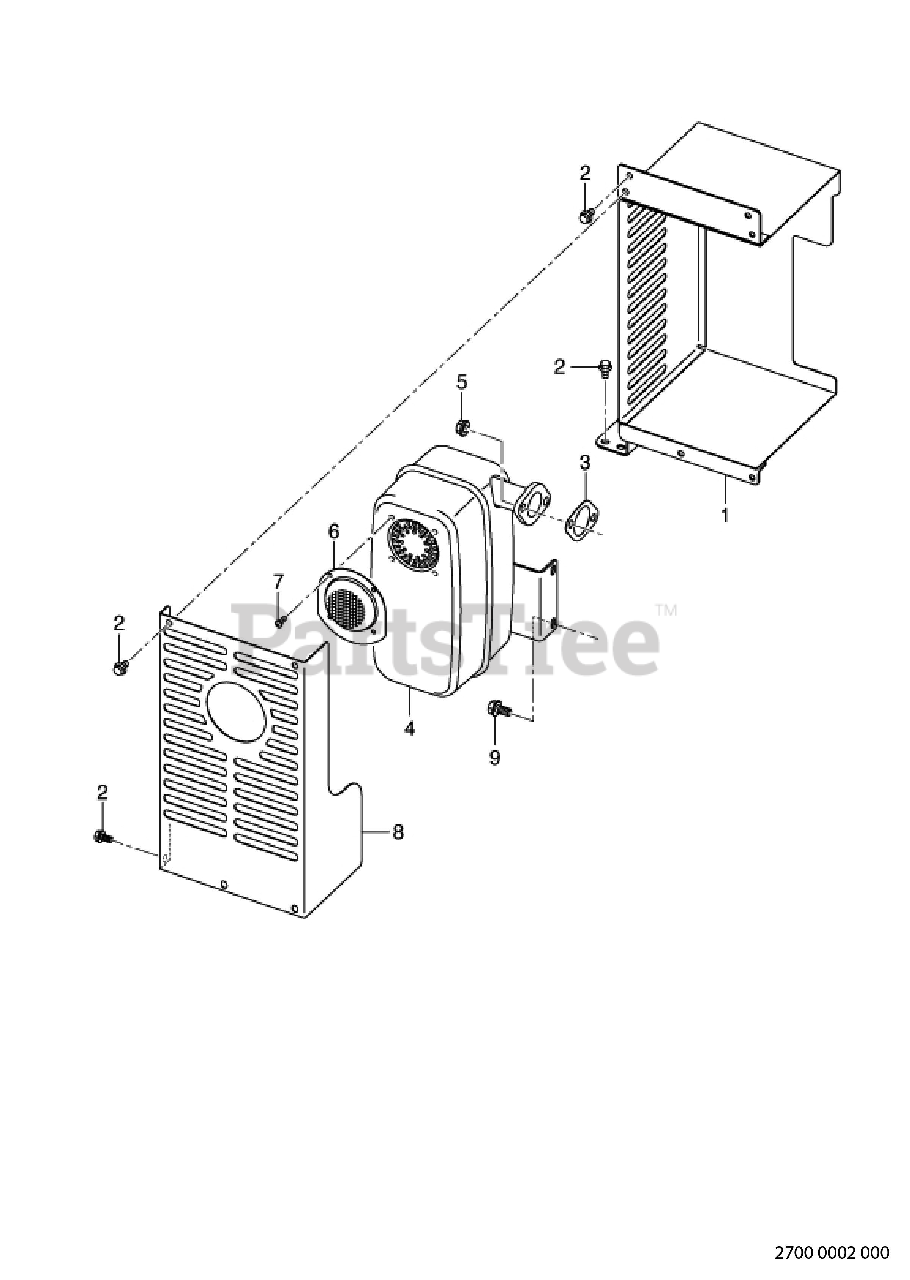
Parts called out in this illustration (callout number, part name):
1	MUFFLER GUARD
2	BOLT
3	GASKET CP (MUFFLER)
4	MUFFLER
6	SPARK ARRESTER
7	SCREW
8	MUFFLER COVER
9	BOLT
